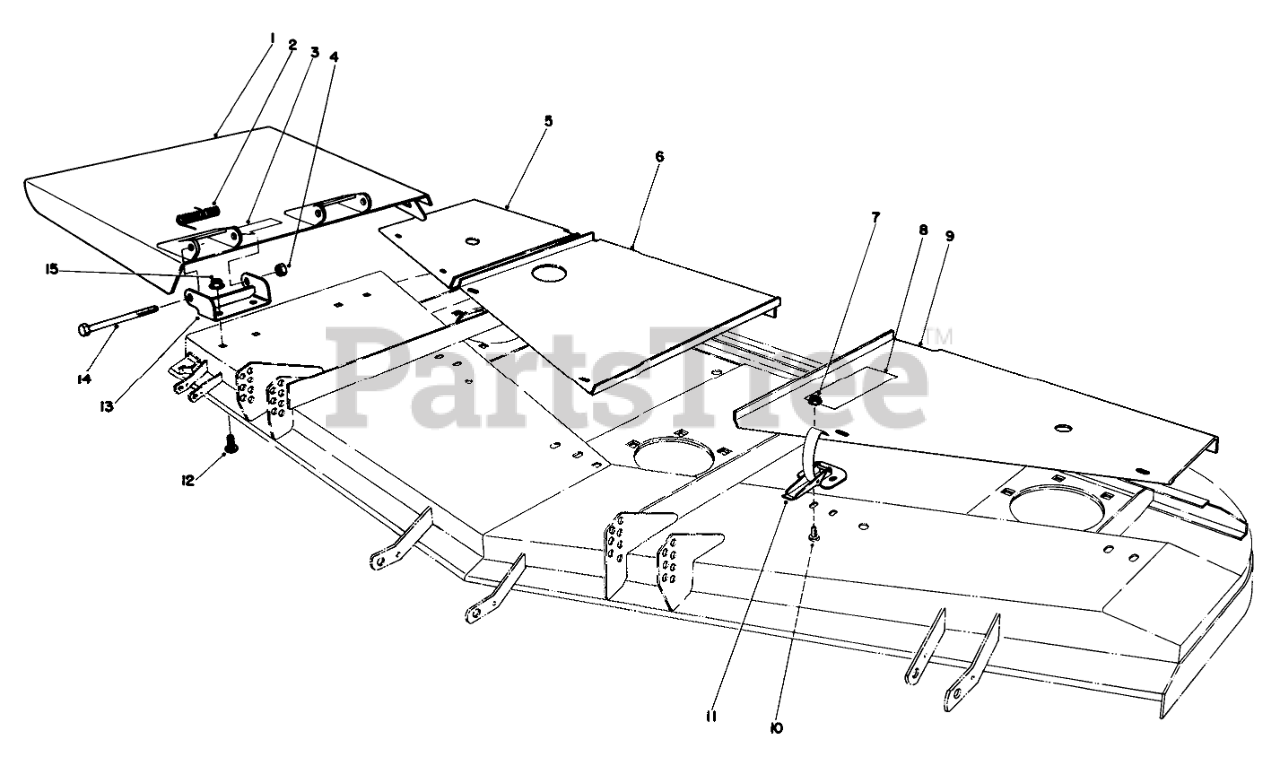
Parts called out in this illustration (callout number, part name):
1	Deflector
2	SPRING
3	DECAL - BLADE LINE
4	NUT-HEX
5	Cover R.H.
6	Cover-Center
7	NUT-LOCK, FLANGE
8	DECAL
9	Cover L.H
10	SCREW-HWH
11	CLAMP-SLOTTED
12	SCREW-CARR
13	Bracket-Hinge
14	SCREW-HH
15	NUT-HHF, WHIZ
